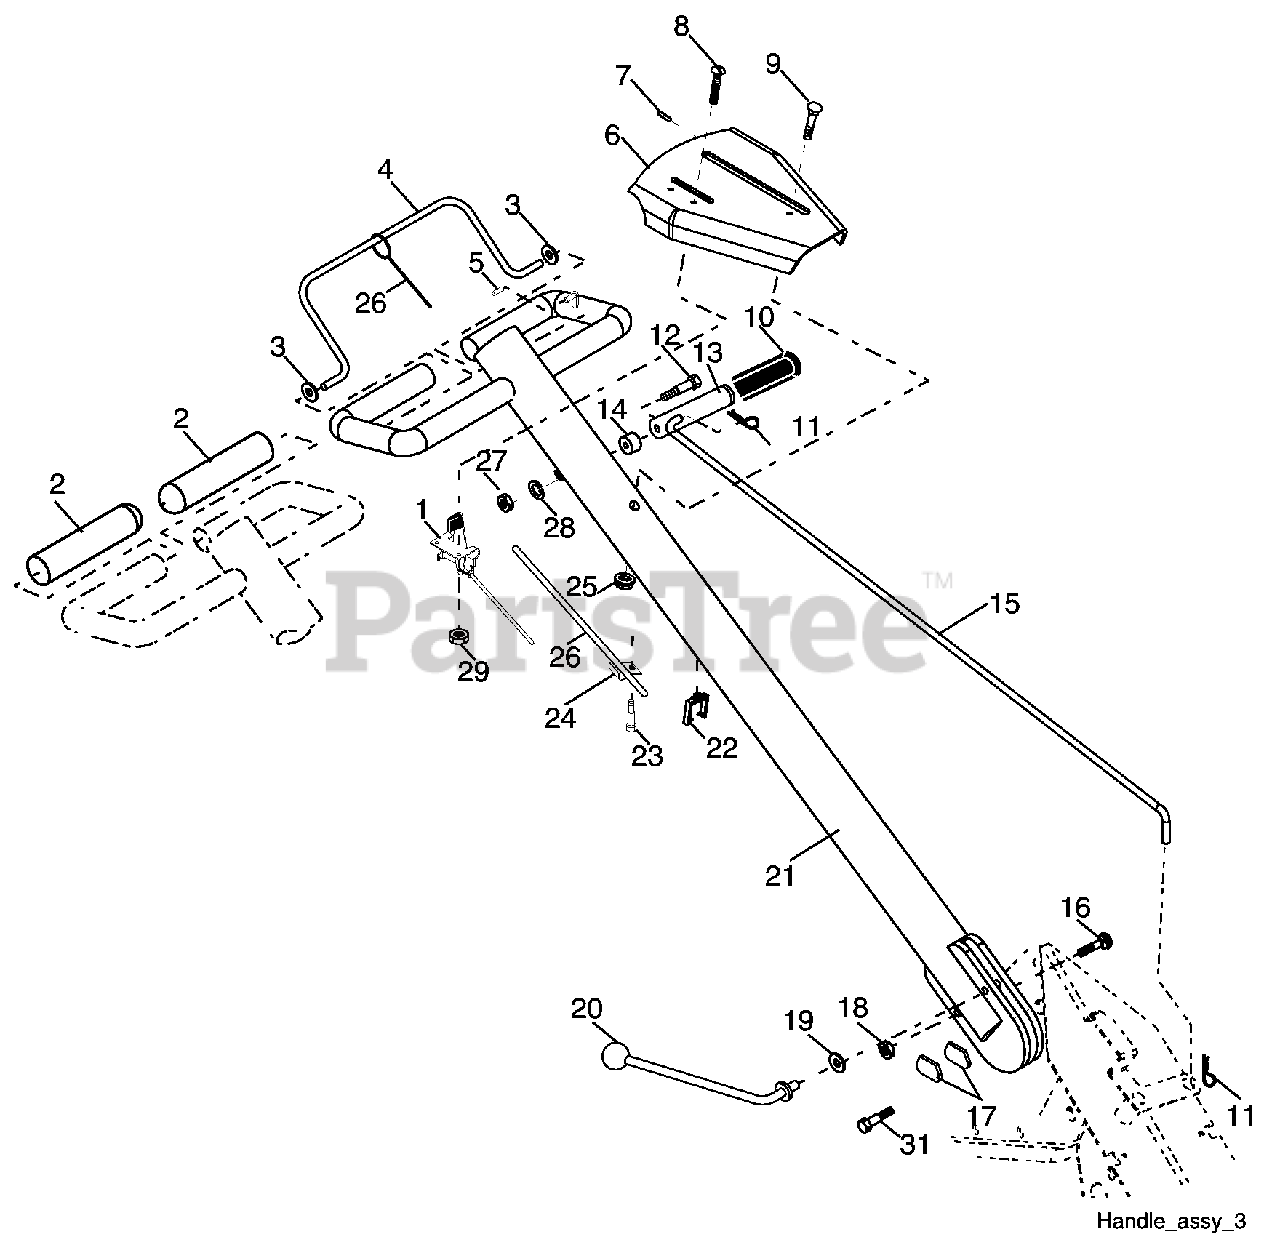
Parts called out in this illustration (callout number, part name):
1	Control, Throttle
2	Grip, Handle
3	Grommet Handle
4	Bar Assembly, Control
6	Panel, Control
7	Bushing Split
8	Screw, Truss Hd. #10-24 Unc x 1/2
9	Bolt 5/16-18 x 2.50
10	Grip, Handle
11	Clip, Hairpin
12	Bolt, Shoulder
13	Handle, Shift
14	Grommet, Rubber
15	Rod, Shift
16	Bolt, Carriage 3/8-16 x 1 Gr. 5
17	Lock, Handle
18	Nut, Crownlock 3/8-16 Unc
19	Washer 13/32 x 1 x 11 Ga.
20	Lever, Lock, Handle
21	Handle
22	Clip Cable
23	Screw, Hex Washer Hd. Slotted #10-24 x 1/2
25	Nut Lock Hex Flange
26	Cable, Clutch
27	Nut Hex Flange 1/4-20 Unc
29	Nut, Keps #10-24 Unc
31	Bolt, Pivot
